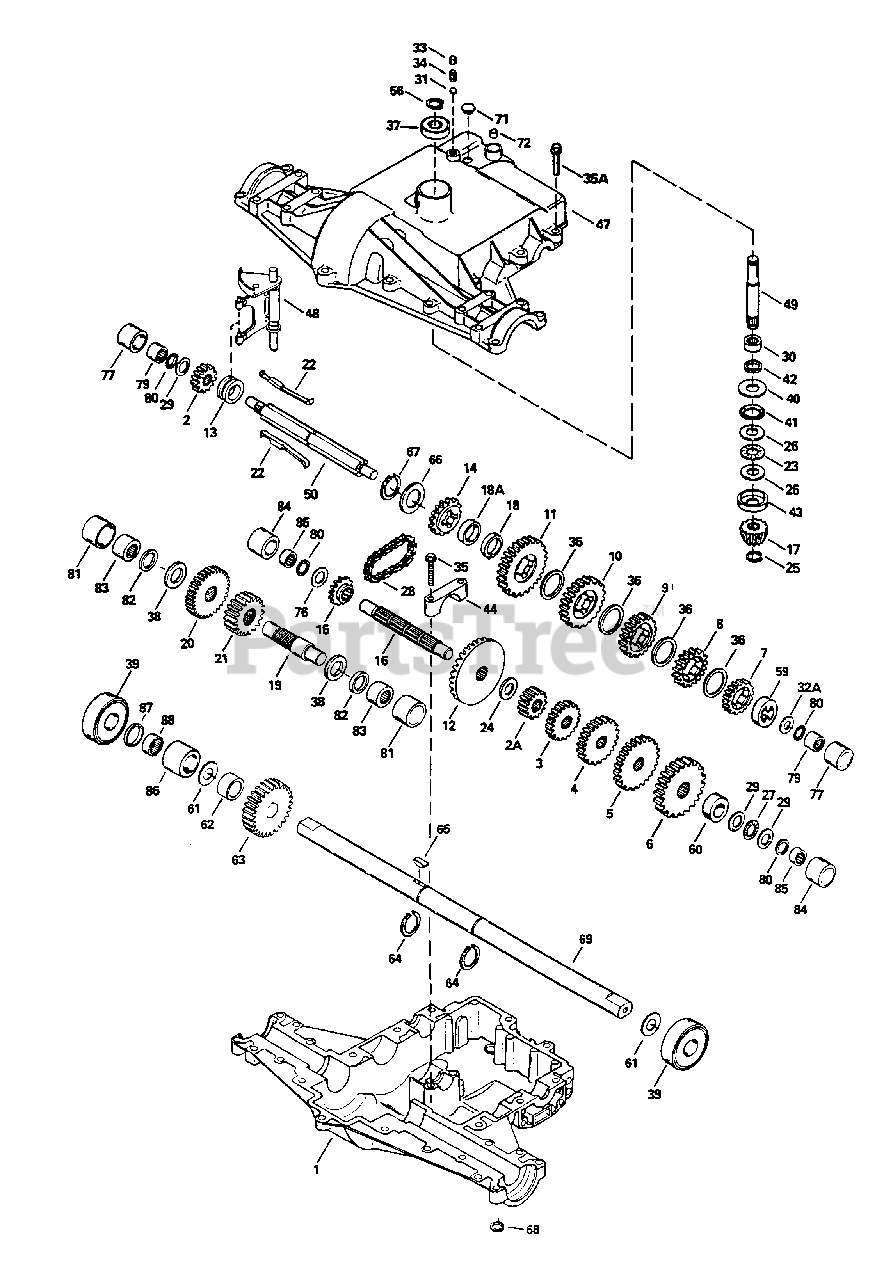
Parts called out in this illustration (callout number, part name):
1	CASE, Transaxle
2	GEAR, Spur (19 Teeth)
2A	GEAR, Spur (15 Teeth)
3	GEAR, Spur (23 Teeth)
4	GEAR, Spur (25 Teeth)
5	GEAR, Spur (28 Teeth)
6	GEAR, Spur (31 Teeth)
7	GEAR, Spur (19 teeth)
8	GEAR, Spur (22 Teeth)
9	GEAR, Spur (25 Teeth)
10	GEAR, Spur (27 Teeth)
11	GEAR, Spur (35 Teeth)
12	GEAR, Bevel (33 Teeth)
13	COLLAR, Shifter
14	SPROCKET (18 Teeth)
15	SPROCKET (18 teeth)
16	SHAFT, Counter
17	BEVEL PINION, Input (13 Teeth)
18	SPACER, Neutral (.350/.340 Thick)
18A	SPACER, Neutral (.276/.268 Thick)
19	SHAFT, Output
20	GEAR, Output (31 Teeth)
21	GEAR, Spur (19 Teeth)
22	KEY, Shifter
23	BEARING, Thrust
24	WASHER, Thrust
25	* RING, Retaining
26	WASHER, Thrust
27	BEARING, Thrust
28	CHAIN, Roller (No. 41 chain, 24 links)
29	* WASHER, Thrust
30	BEARING, Needle
31	BALL, Steel (5/16" dia.)
32A	WASHER, Thrust
33	SCREW, Set, 3/8-16 x 3/8
35	Screw 1/4-20 x 1-1/4"
35A	SCREW, Hex Hd. Threadforming, 5/16-18 x 1-1/4
36	* WASHER, Thrust
37	BEARING, Ball
38	WASHER, Thrust
39	BEARING, Ball
40	Thrust Washer
43	WASHER, Cupped
44	CAP, Bearing
47	COVER, Transaxle
48	ROD & FORK ASSY., Shift
49	SHAFT, Input
50	SHAFT, Brake
59	SPACER, (1-3/8" O.D. x 1-1/8" I.D. x 3/8" Thick)
60	SPACER, (1-1/8" O.D. x 3/4" I.D. x 3/8" Thick)
61	WASHER, Thrust, 1.542 OD x 1.007 ID x .060 thick
63	GEAR, Spur (27 Teeth)
64	RING, Retaining
65	KEY, Woodruff
66	WASHER, Thrust
67	RING, Retaining
68	SEAL, Rubber
69	AXLE (22-5/8" Long)
71	PLUG, Hex Hd., 9/16-18 thread
72	PLUG, Expansion
79	BEARING, Needle (Capped)
80	RING, Square Cut
81	SLEEVE (Stepped)
82	RING, Square Cut
83	BEARING, Cartridge
85	BEARING, Needle (Capped)
86	SLEEVE (Stepped)
87	RING, Square Cut
